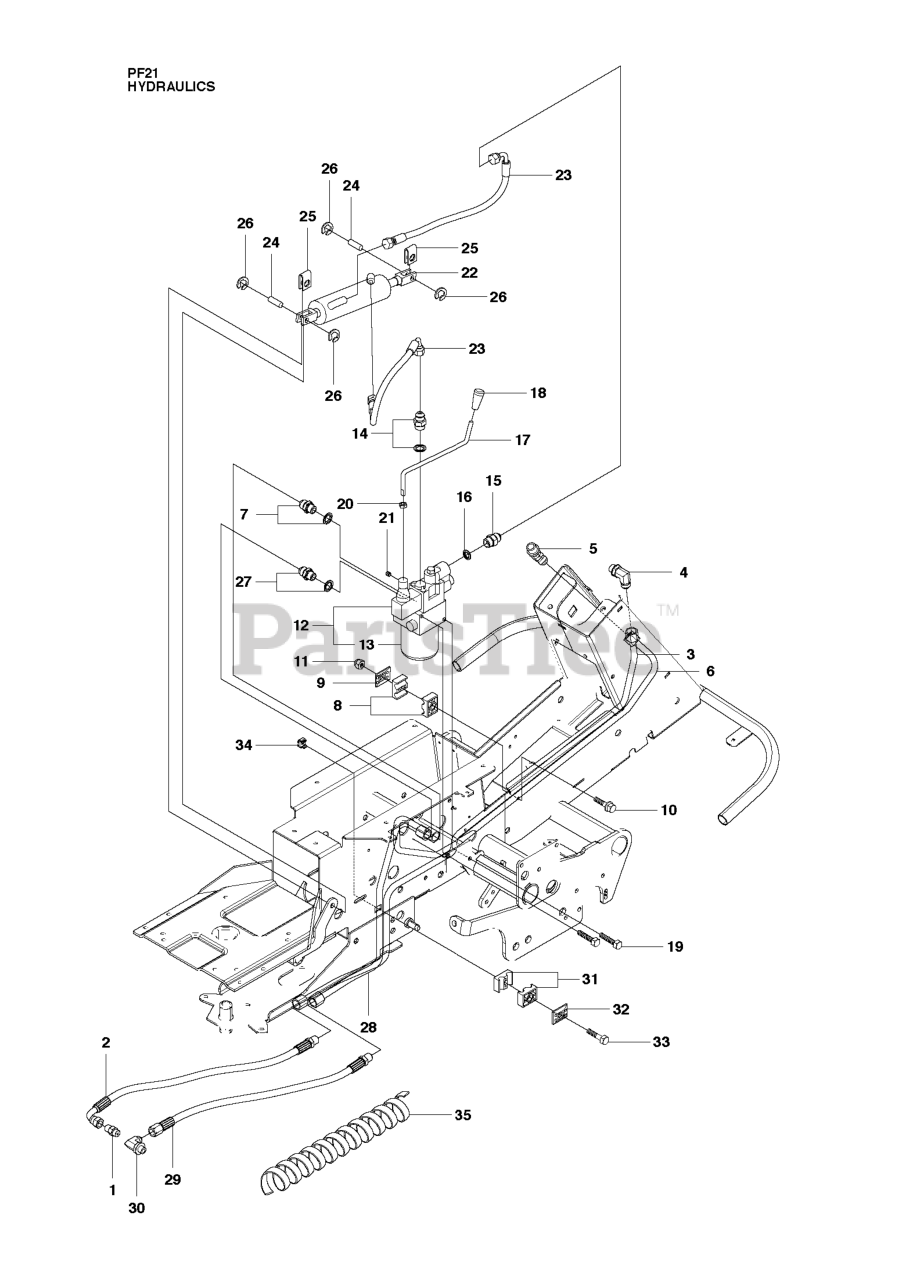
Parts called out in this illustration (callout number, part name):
8	PIPE CLAMP
11	LOCKNUT M6
13	FILTER
19	REPL BY 725 24 49-51
20	NUT
26	RETAINING RING SGA 10
31	PIPE CLAMP
